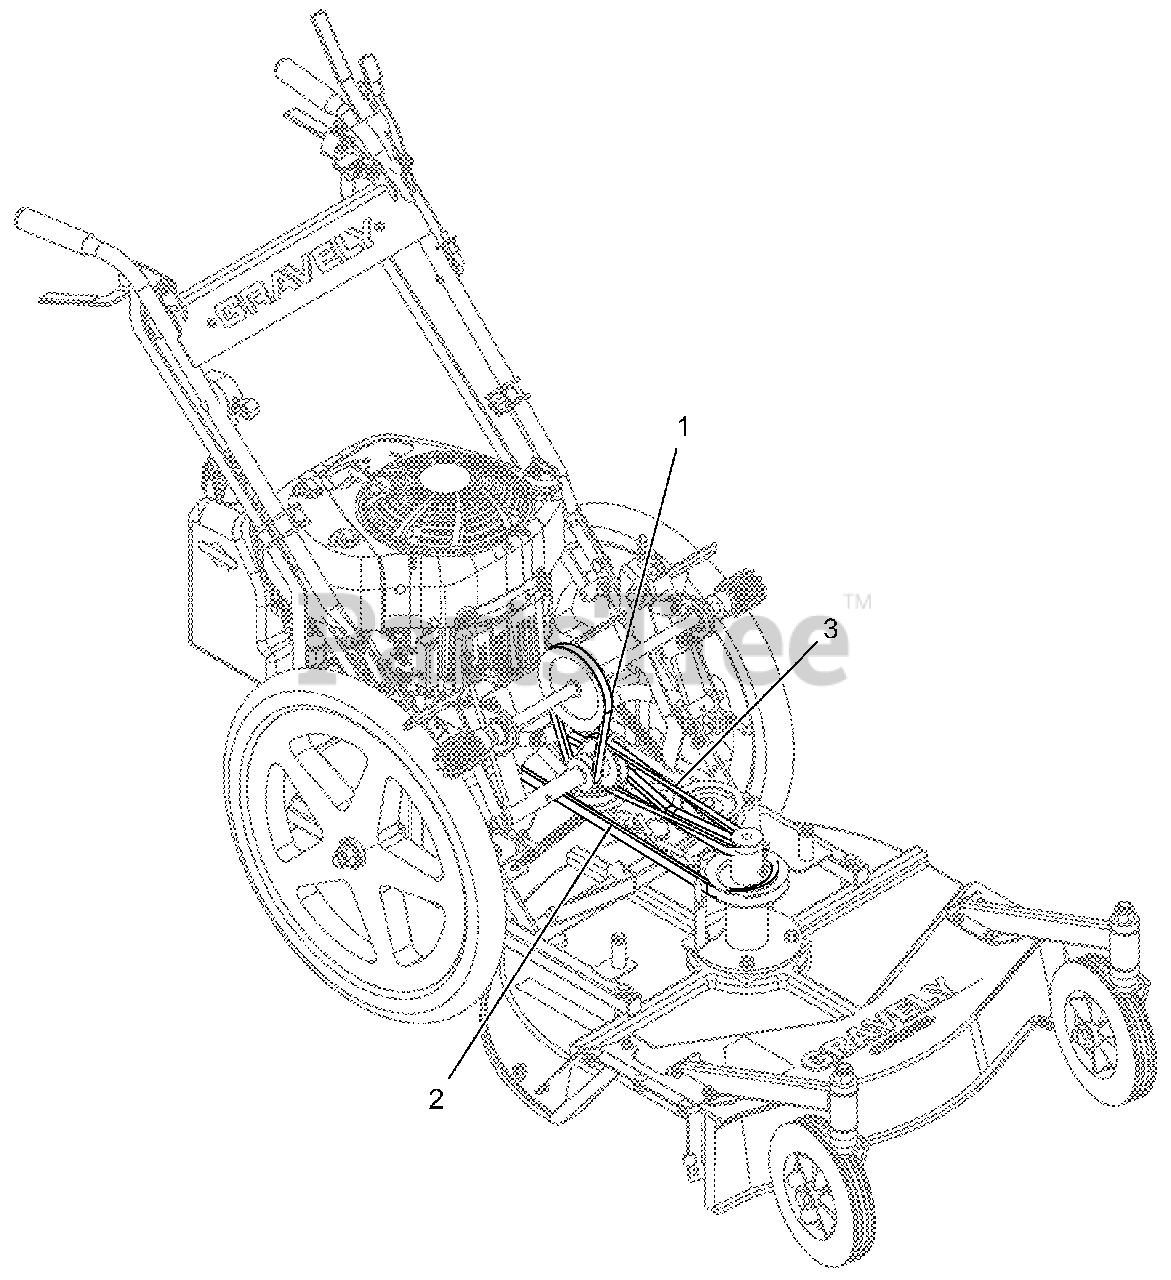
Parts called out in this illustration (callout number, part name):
1	V-BELT, 4L-RAW EDGE
2	V-BELT, 5L-WRAPPED
3	V-BELT, 4L-RAW EDGE
